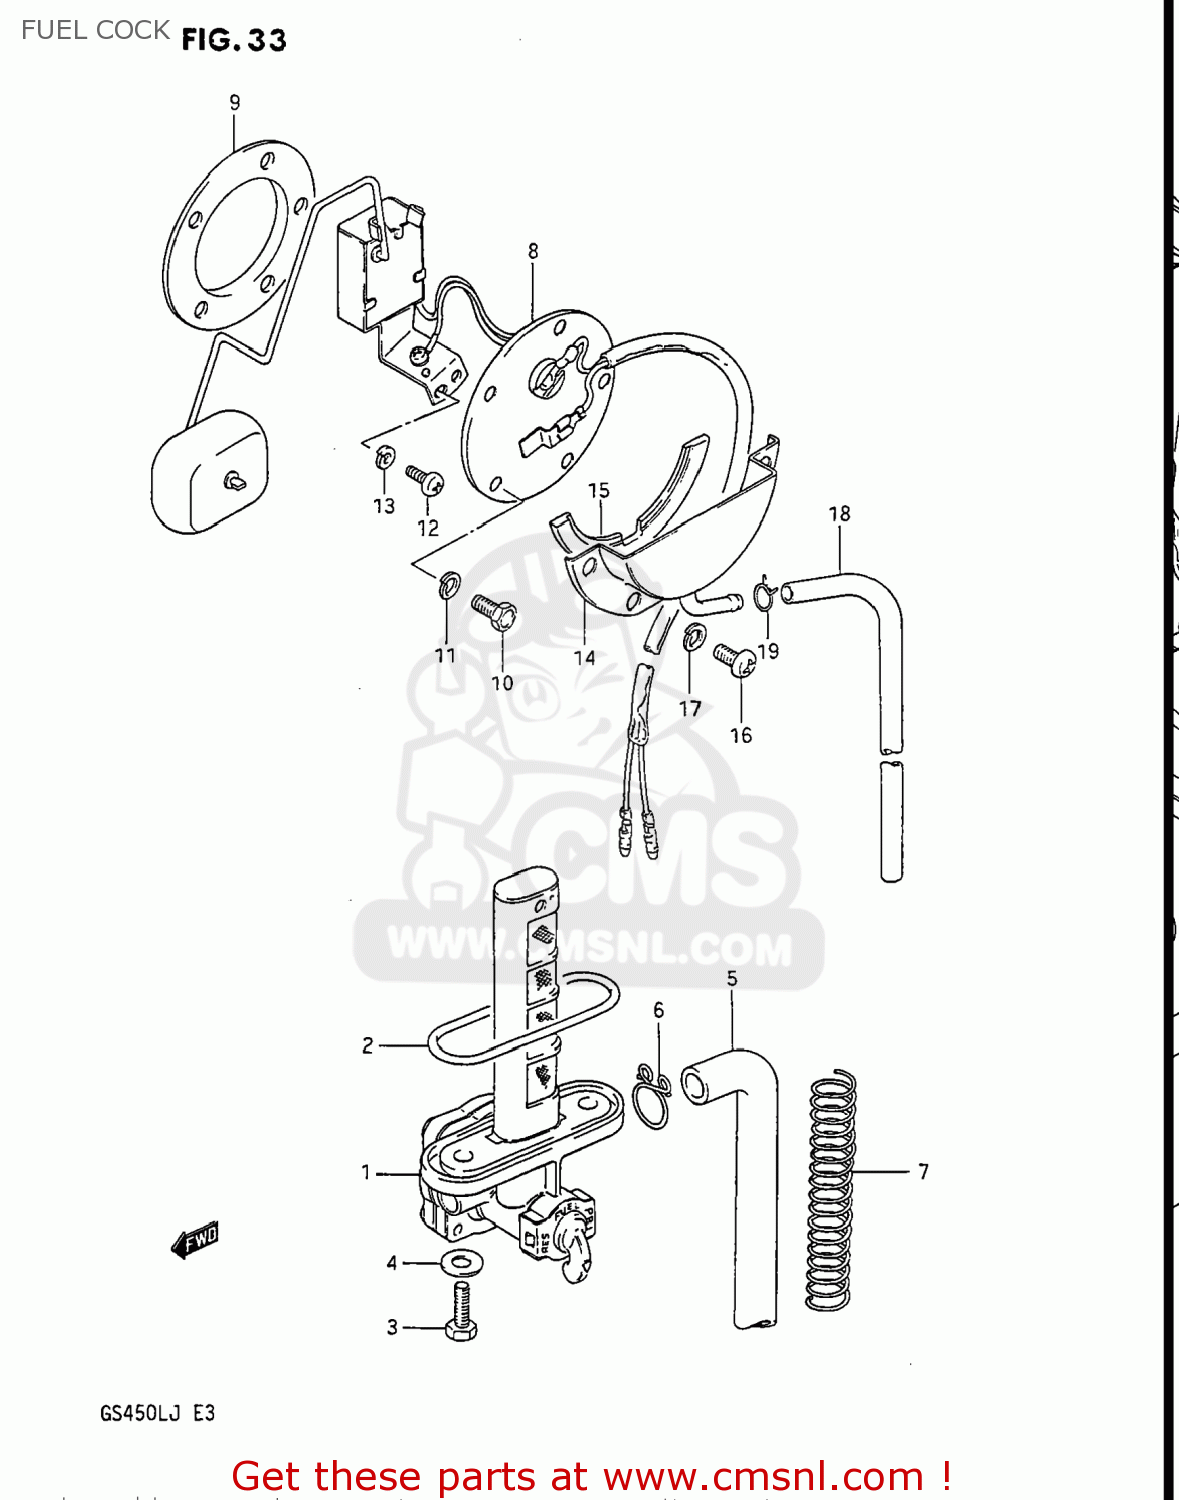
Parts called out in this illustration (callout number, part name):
1	COCK ASSY,FUEL
2	O RING
3	BOLT(6X20)
4	GASKET
5	HOSE
6	CLIP
7	SPRING
8	GAUGE ASSEMBLY,FUEL LEVEL
9	GASKET,FUEL LEVEL GAUGE (NAS)
10	BOLT
11	LOCK WASHER
12	SCREW 5X10
13	LOCK WASHER
14	PLATE,FUEL DRAIN
15	GASKET (NAS)
16	SCREW
17	LOCK WASHER
18	HOSE
19	CLIP
